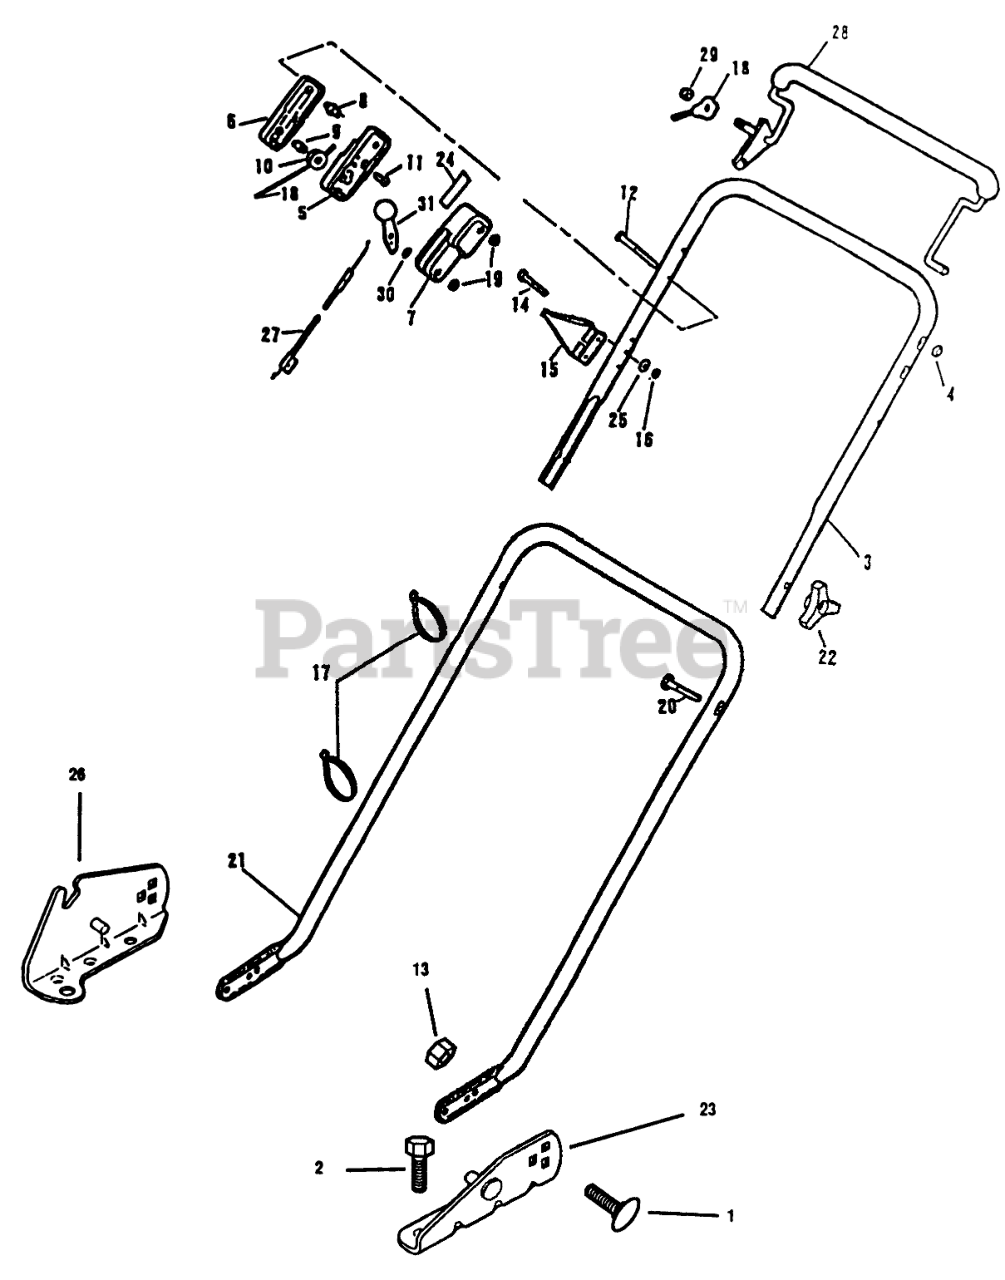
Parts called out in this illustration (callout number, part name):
1	Bolt
2	SCREW
3	Handle-Top
4	NUT-PUSH
5	CENTER CONTROL CASE
6	OUTER CONTROL CASE
7	INNER CONTROL CASE
8	COLUMN
9	PIN SKF
10	PULLEY PL
11	SCREW
12	SCREW
13	NUT WING
14	SCREW
15	GUIDE - ROPE
16	LOCKNUT E
17	TIE-CABLE
18	CONTROL CABLE
19	NUT C/LOCK E
20	Screw
21	Handle-Lower
22	Knob
23	ASM-Bracket & Pin
24	DECAL-THROT CONTRL
25	WASHER
26	ASM-Bracket & Pin
27	CABLE TH'TTLE WES
28	CONTROL LEVER ARG
29	NUT ACORN
30	WASHER-SPRING
31	LEVER&KNOB AY WES
